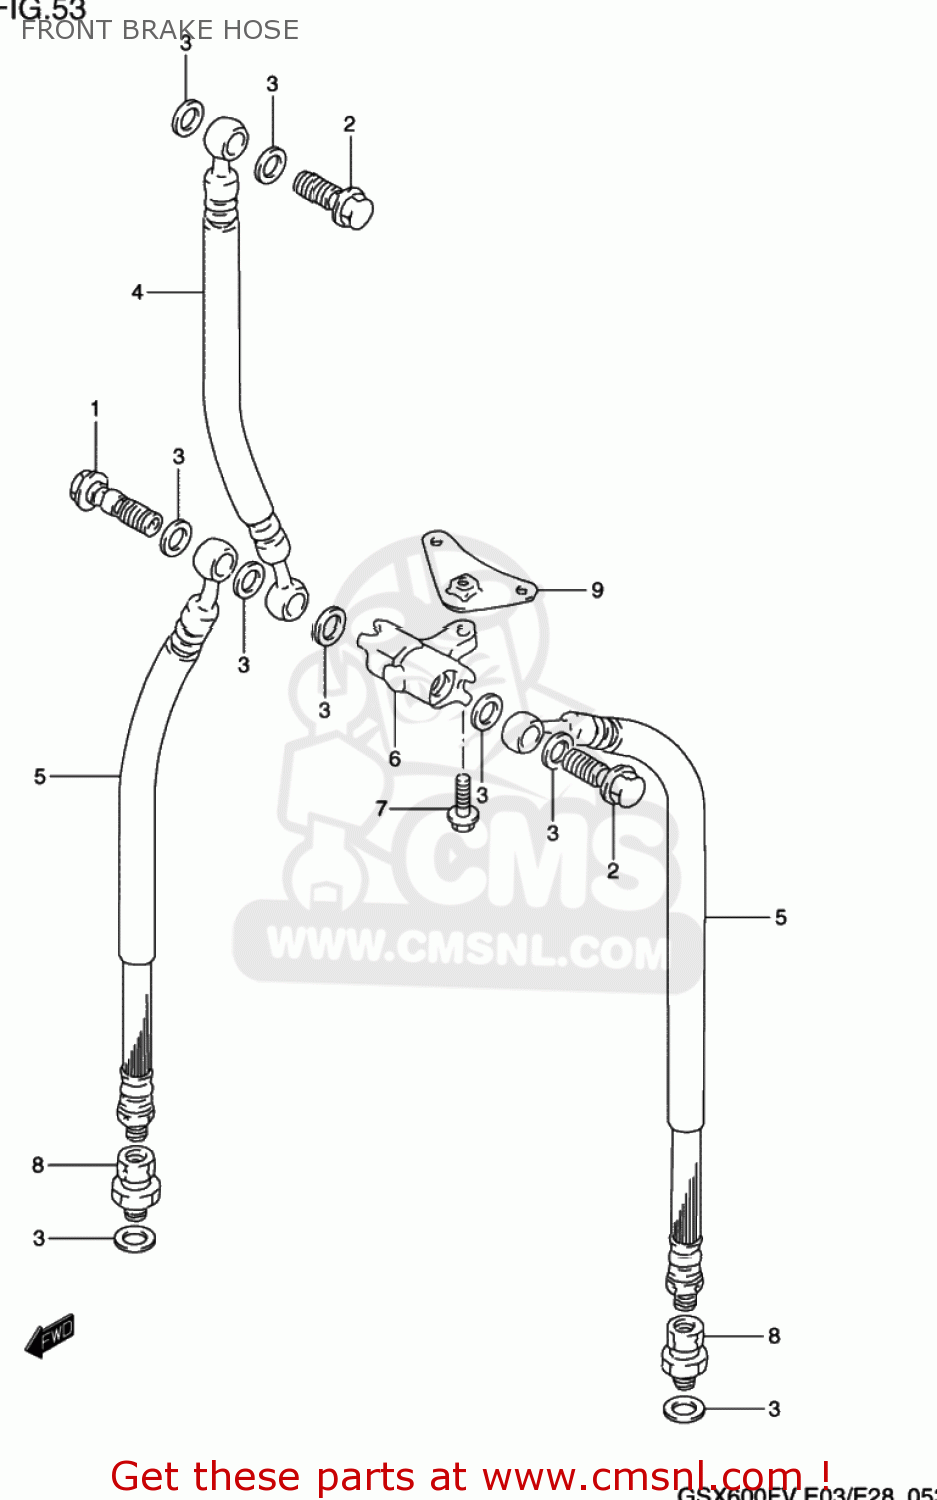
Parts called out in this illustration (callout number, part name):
1	BOLT UNION
2	BOLT UNION
3	WASHER(10X15X1.5)
4	HOSE,FR BRAKE NO.1
5	HOSE,FR BRAKE NO.2
6	JOINT,BRAKE HOSE
7	BOLT
8	ADAPTER,BRAKE HOSE
9	PLATE,FRONT BRAKE JOINT
